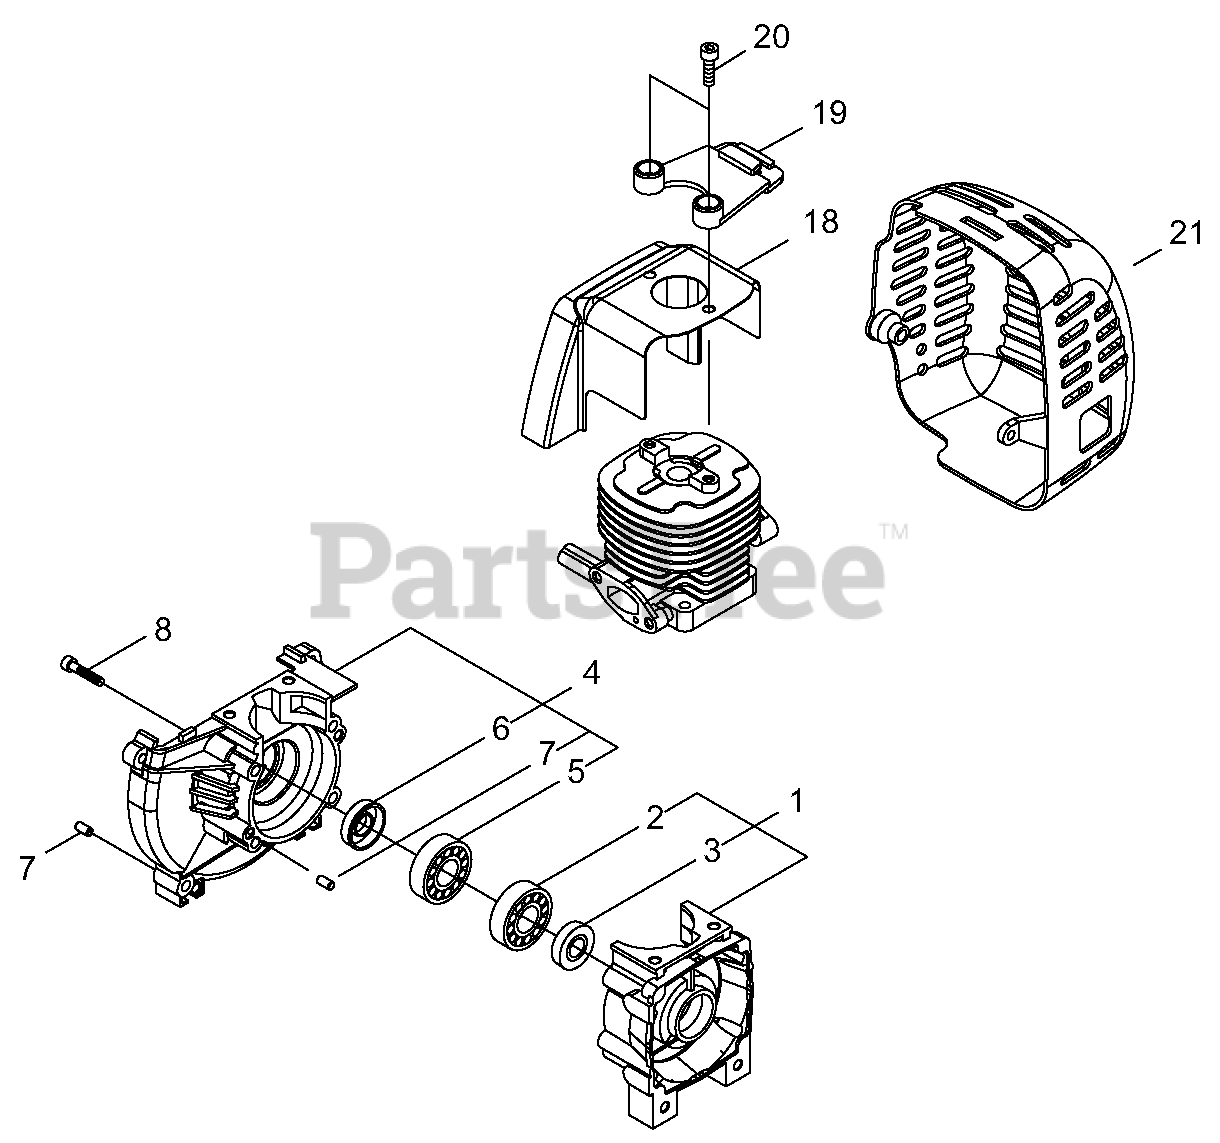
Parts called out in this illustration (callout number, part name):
1	CRANKCASE ASSY - REAR
2	BEARING, BALL - 6202C3
3	SEAL, OIL - 15
4	CRANKCASE ASSY - FRONT
5	BEARING, BALL - 6202C3
6	SEAL, OIL - 15
7	PIN - LOCATING
8	SCREW - 5X30
18	COVER, ENGINE
19	BRACKET
20	SCREW - 5X18
21	COVER, EXHAUST
